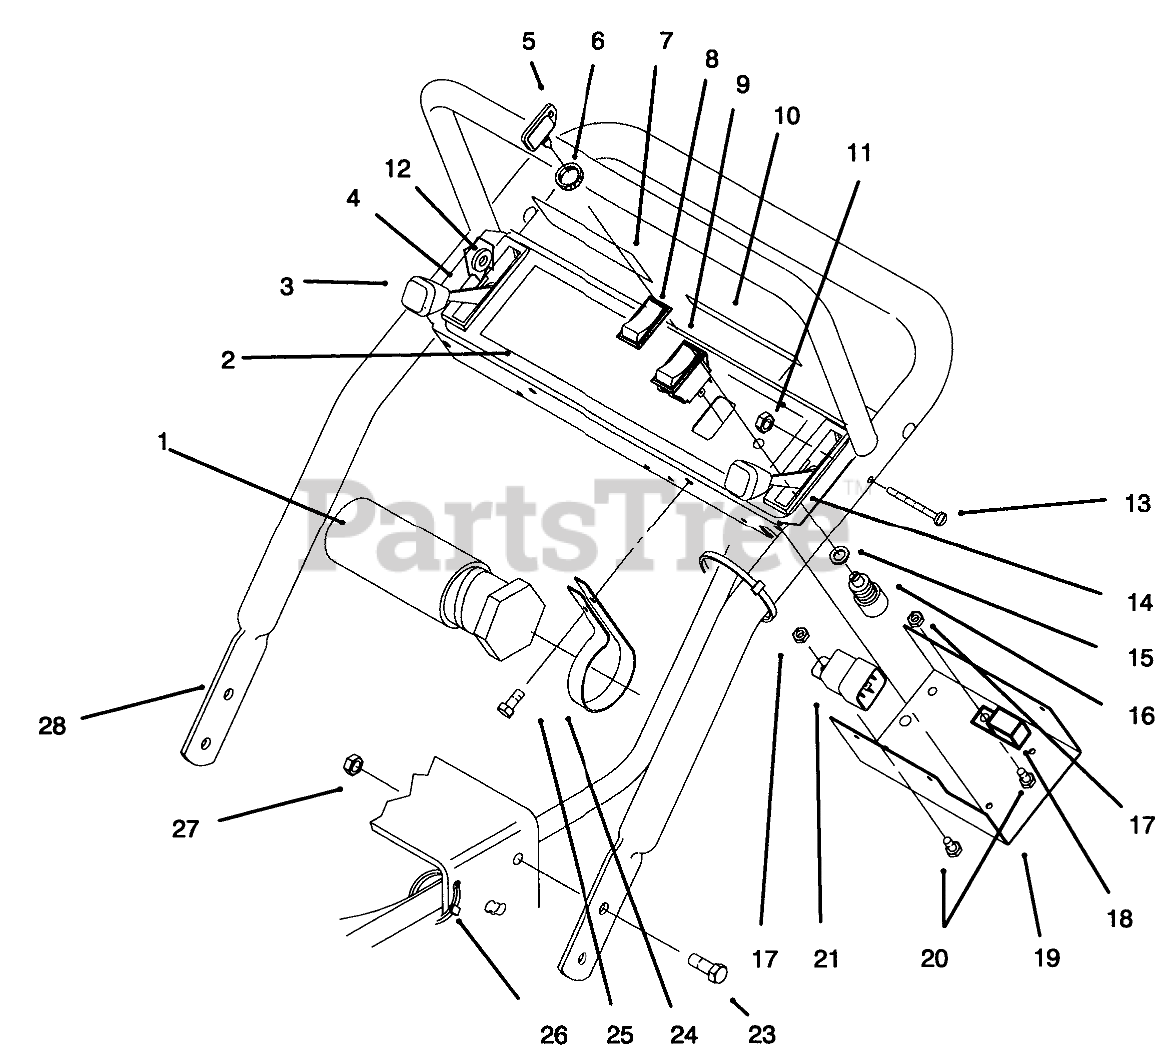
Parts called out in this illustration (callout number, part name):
1	TUBE-MANUAL
2	Decal-Proline
3	Control-Choke
4	Panel-Control
5	KEY-IGNITION
6	NUT-HH
7	DECAL-INSTRUCTION, SAFETY
8	BOOT-SWITCH
9	Switch-Clutch (Incl. Ref.#8)
10	DECAL-INSTRUCTION
11	NUT-LOCK, NI
12	SPACER
13	SCREW-SHH
14	CONTROL - THROTTLE
15	WASHER-TOOTH, INTERNAL
16	Switch-Ignition (Incl. Ref. #5,6, &15)
17	NUT-LOCK, NI
18	Module
19	Panel-Bottom
20	SCREW-HH
21	RELAY
23	SCREW-HHF
24	CLAMP-R
25	SCREW-SHWH
26	TIE-CABLE
27	NUT-HF
28	Handle-Upper
